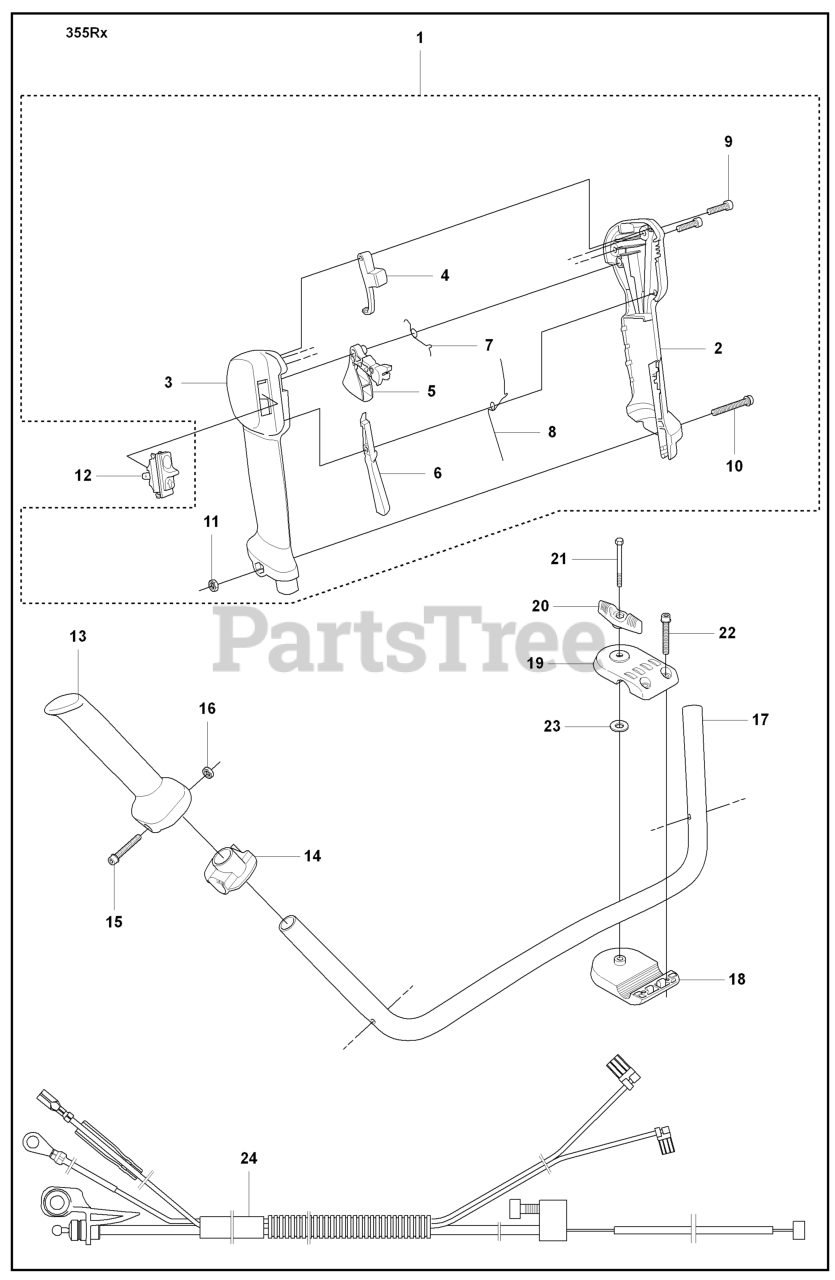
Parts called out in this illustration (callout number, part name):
2	HANDLE HALF RIGHT
3	HANDLE HALF LEFT
4	LOCKOUT STARTER THROTTLE
5	THROTTLE TRIGGER
6	THROTTLE LOCK
10	SCREW
12	STOP BUTTON
16	NUT M6M M5
17	HANDLE
18	HANDLE HOLDER LOWER
19	HANDLE HOLDER UPPER
21	%SCREW
